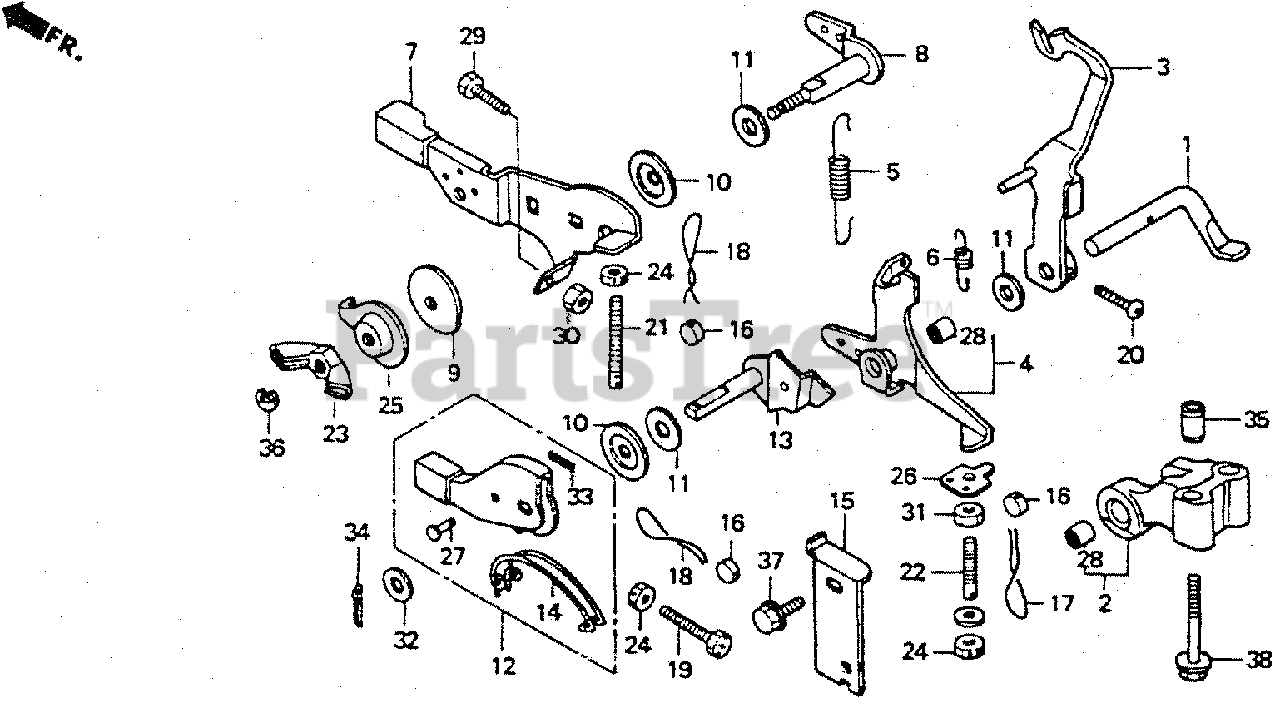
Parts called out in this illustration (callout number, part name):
1	SHAFT, GOVERNOR ARM
2	STAY, GOVERNOR SHAFT
3	ARM, GOVERNOR
4	ARM, SUB-GOVERNOR
5	SPRING, GOVERNOR
6	SPRING, IDLE
7	LEVER, CONTROL
8	SHAFT, CONTROL LEVER
9	SPRING, LEVER
10	SPACER, CONTROL LEVER (A)
11	SPACER, CONTROL LEVER (B)
12	LEVER, STOP
13	SHAFT, STOP LEVER
14	SPRING, STOP LEVER
15	HOLDER, STOP CABLE
16	END, LOCK
17	WIRE, LOCK (A)
18	WIRE, LOCK (B)
19	BOLT, RECESSED (6X32)
20	SCREW, PAN (3X18)
21	BOLT, CONTROL ADJUSTING
22	BOLT, ADJUSTING
23	NUT, PLUG COVER
24	NUT, HEX. (6MM)
25	WASHER (6X30)
26	WASHER, SEALING
27	PIN, CENTER (4X16.5)
28	BEARING, NEEDLE (8X12X10) (TOYO)
29	BOLT, SLOT (6X20)
30	NUT, HEX. (6MM)
31	NUT, HEX. (6MM)
32	WASHER, PLAIN (8MM)
33	PIN, COTTER (1.6)
34	PIN, COTTER (2.5MM)
35	PIN A, DOWEL (8X14)
36	E-RING (3MM)
37	BOLT, FLANGE (6X16)
38	BOLT, FLANGE (6X40)
